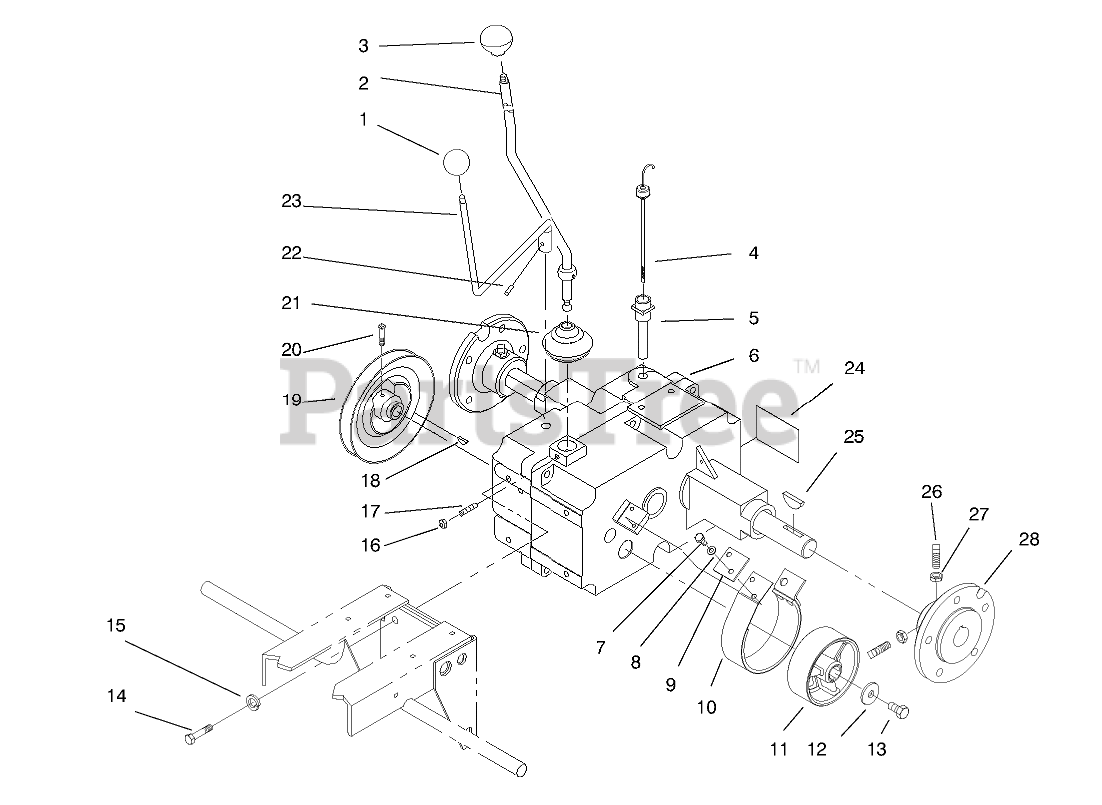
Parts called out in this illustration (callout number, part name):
2	ASM-Rod
4	DIPSTICK
5	NIPPLE-FILL, TRANSMISSION
6	TRANSMISSION ASM
7	SCREW-HH
8	WASHER-LOCK
9	Plate-Stop
10	BRAKE BAND ASM
11	DRUM-BRAKE
12	WASHER
13	SCREW-HEX HD CAP
14	SCREW-HH
15	WASHER-LOCK
16	NUT-HEX
17	SETSCREW
18	KEY-HI PRO
19	PULLEY-TRANSMISSION
20	SCREW-SQH
21	COVER-DUST
22	PIN-SPIROL
23	SHIFT ROD ASM
24	DECAL-UNIDRIVE
25	KEY-WOODRUFF
26	SCREW-SET, SQH
27	NUT-JAM
28	HUB-WHEEL
